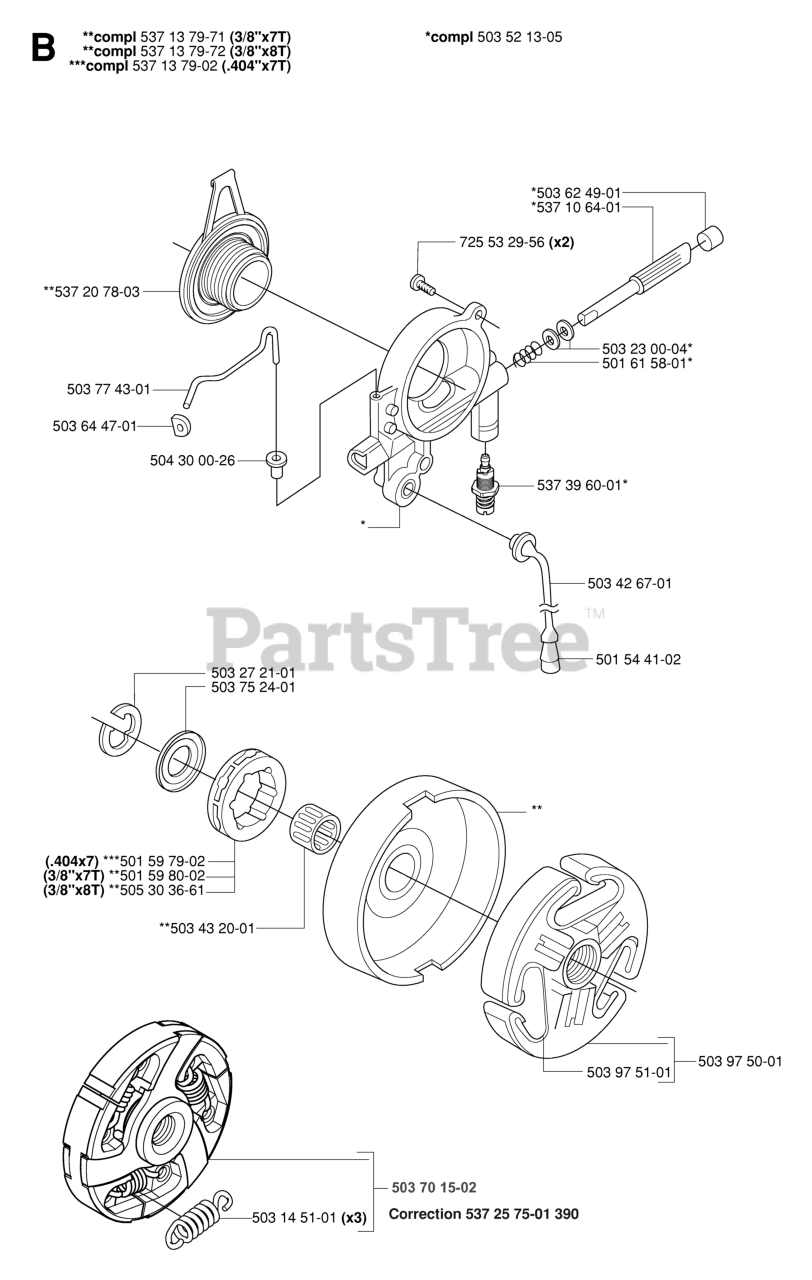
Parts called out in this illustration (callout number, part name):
1	WIRE ASM INNER W/ PLUNGER LT
2	SHAFT ASM R HANDLE
3	PIN GROOVE.
4	RETAINING RING LT
6	BEARING.NYLON
8	PLUNGER BUT KIT
11	LINK LIFT LH
12	LINK LIFT RH
13	RETAINER-SPRNG RB
15	LINK.SUSPENSION.FRONT
16	NUT.HEX.JAM.1/2-13
18	NUT.LK.W/WSH.1/2.
19	ARM.REAR.SUSPENSION
20	SPRING RETAINER
31	BEARING.PIVOT.LIFT
32	NUT CROWNLOCK 3/8-24
